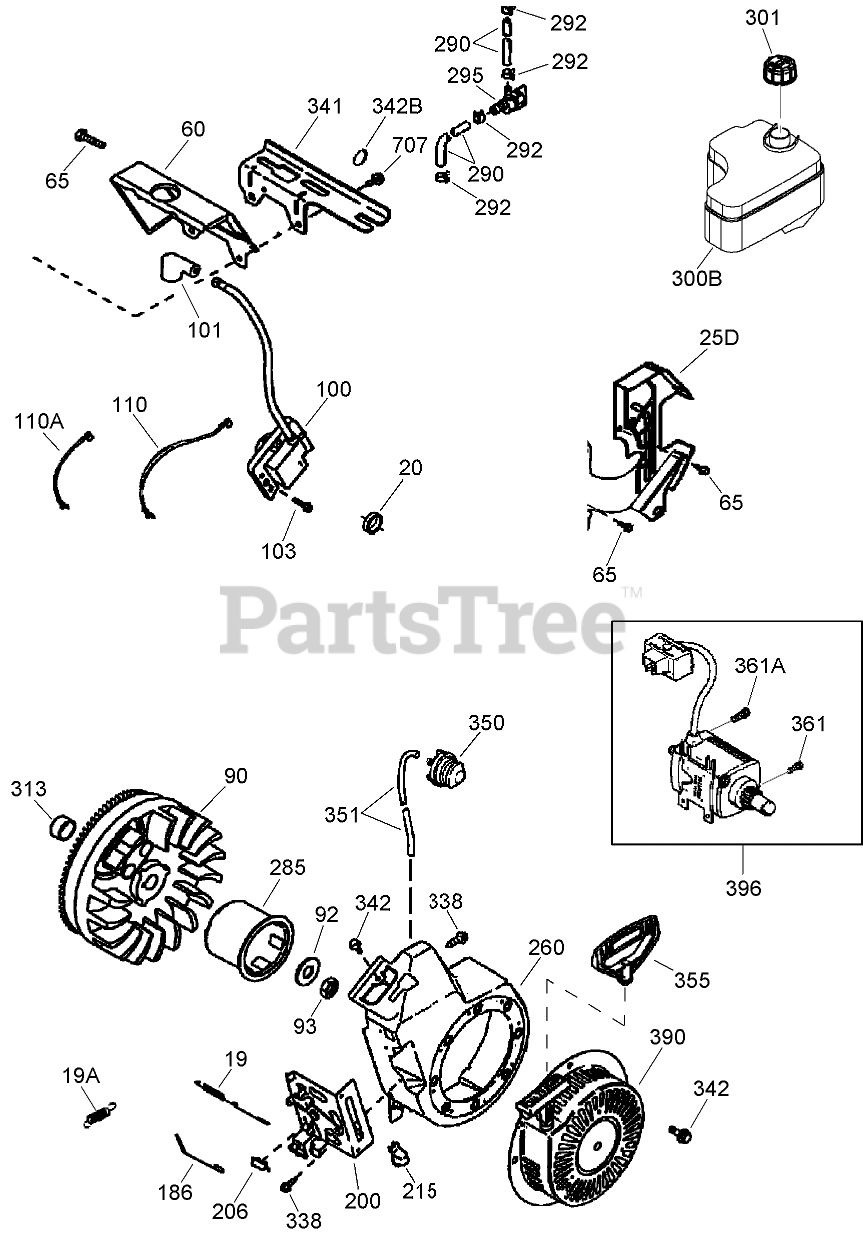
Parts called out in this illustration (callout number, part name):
19	Spring-Throttle
19A	Spring-Governor
20	Seal-Oil
25D	Baffle-Air (1 Piece, Electric Start)
60	Extension-Housing, Blower
65	Screw (10-24 x 9/16)
90	Flywheel (18 Watt, Ring Gear)
92	Washer-Belleville
93	Nut-Flywheel
100	Ignition-State, Solid
101	Cover-Spark Plug
103	Screw (T-15, 10-24 x 15/16)
110	Wire-Ground (Green, 9.0)
110A	Wire-Ground (Green, 5.5)
186	Link-Governor
200	Bracket-Control (Includes 206 and 215)
206	Terminal
215	Knob-Control
260	Housing-Blower
285	Cup-Starter
290	Line-Fuel, Low Permeation (8.62)
290	Line-Fuel, Low Permeation (16.0)
292	Clamp-Line, Fuel
295	Valve-Shut-Off, Fuel (Includes 292) (also available in Packaged Part 740073)
300B	Fuel Tank ASM (Includes 292 and 301) 3.5 Quart
301	Cap-Fuel (Red Plastic) (1-1/2 ID)
313	Spacer
338	Screw (10-32 x 1/2)
341	Bracket-Tank, Fuel
342	Screw (1/4-20 x 31/64)
342B	Washer-Rubber
350	Primer ASM (also available in packaged Part 740101)
351	Line-Primer
355	Handle-Starter, Mitten Grip
361	Screw (T-30, 1/4-20x15/32)
361A	Screw
390	Starter-Rewind
396	Electric Starter Motor 220 Volt
707	Screw (1/4-20 x 19/32)
